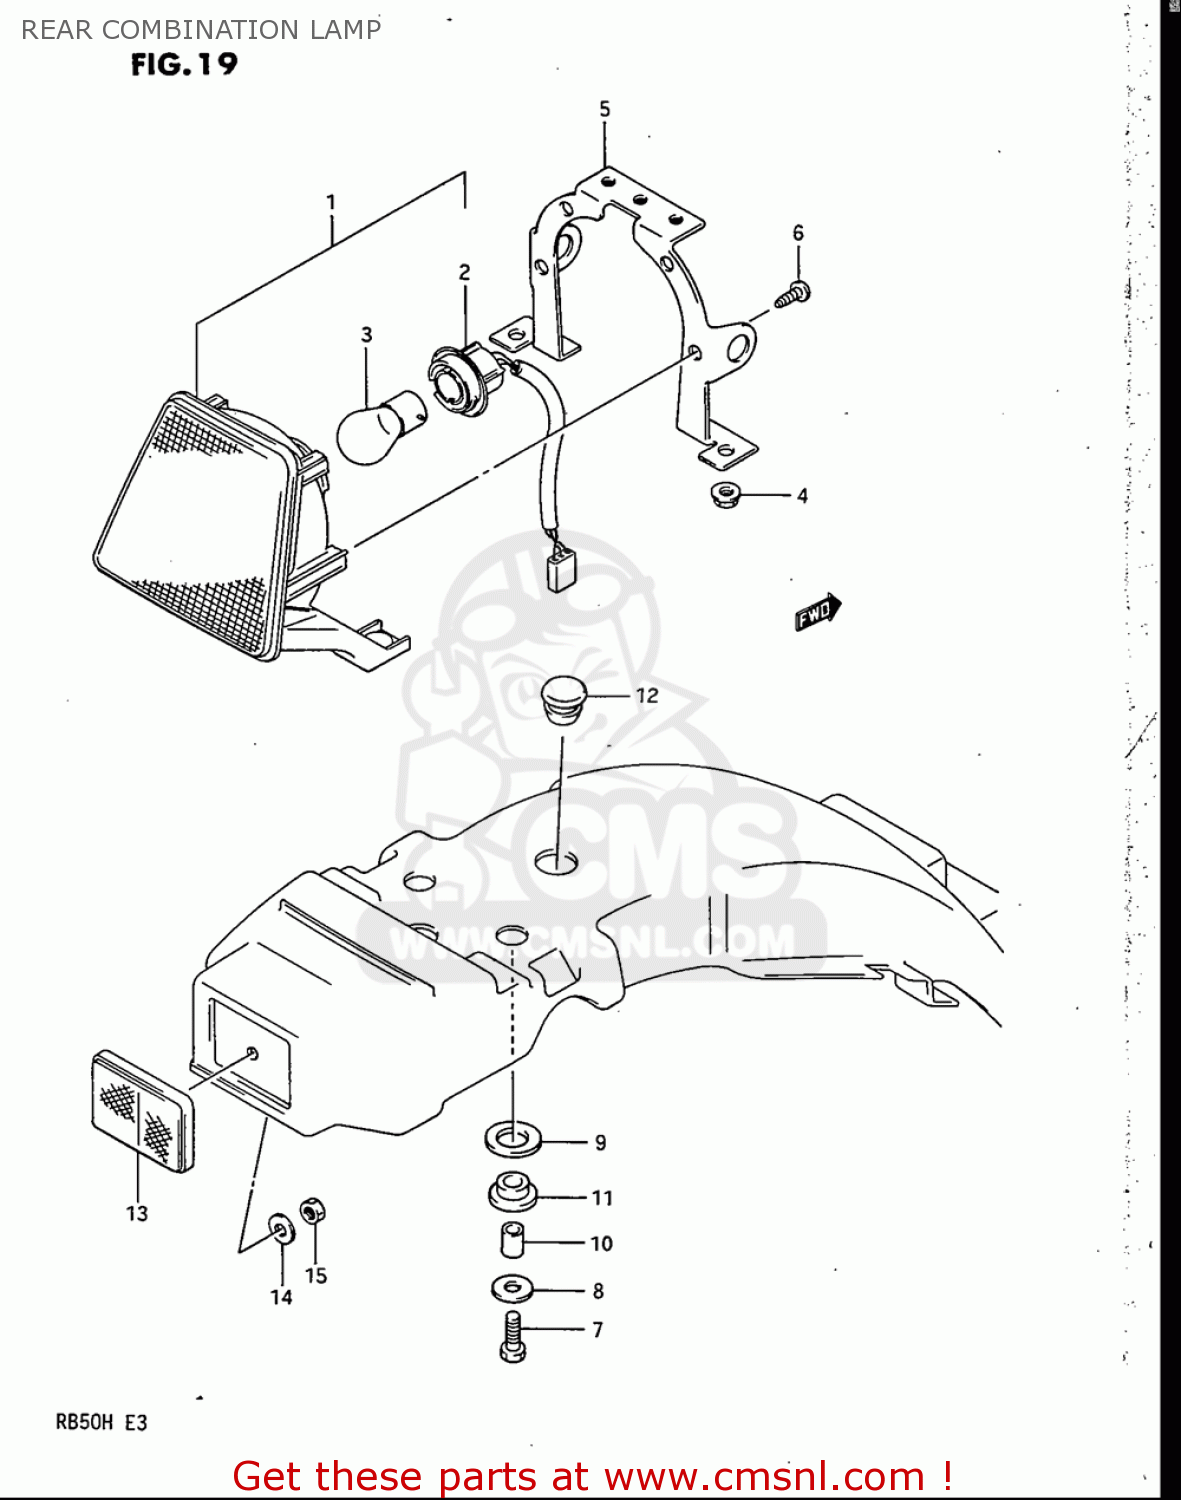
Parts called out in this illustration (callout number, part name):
1	LAMP ASSEMBLY,REAR COMBINATION
2	SOCKET & CORD ASSEMBLY
3	BULB(6V10/3W,STANLEY,A4854H)
4	NUT
6	SCREW
7	BOLT
8	WASHER(6.5X18X1.6)
9	WASHER(14.2X26X1.2)
10	SPACER(6.5X9X9)
12	CAP(OD:17)
13	REFLEX REFLECTOR,RR
14	WASHER(5.2X16X1)
15	NUT
